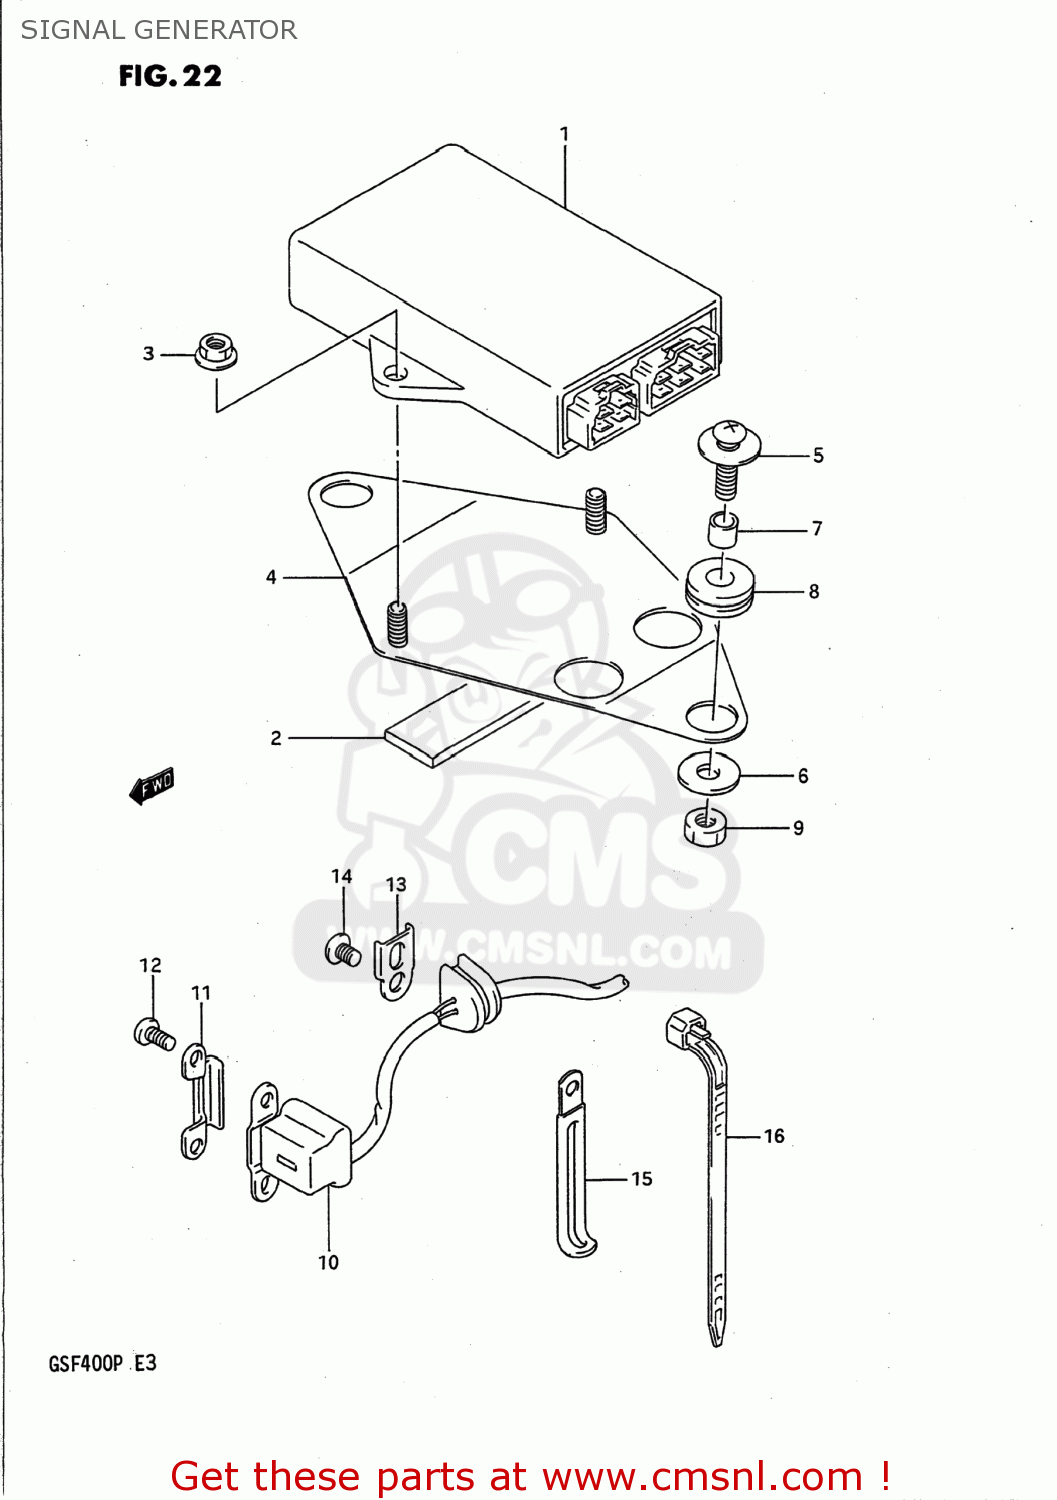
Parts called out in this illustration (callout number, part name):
1	IGNITOR
2	PROTECTOR,20X9
3	NUT
4	PLATE,IGNITOR
5	SCREW(6X20)
6	WASHER
7	SPACER (6.4X9X10.5)
8	CUSHION
9	NUT
10	GENERATOR ASSY,SIGNAL
11	PROTECTOR,SIGNAL GEN LEAD WIRE
12	SCREW
13	CLAMP,GENERATOR LEAD WIRE
14	SCREW
15	CLAMP
16	CLAMP(L:125)
